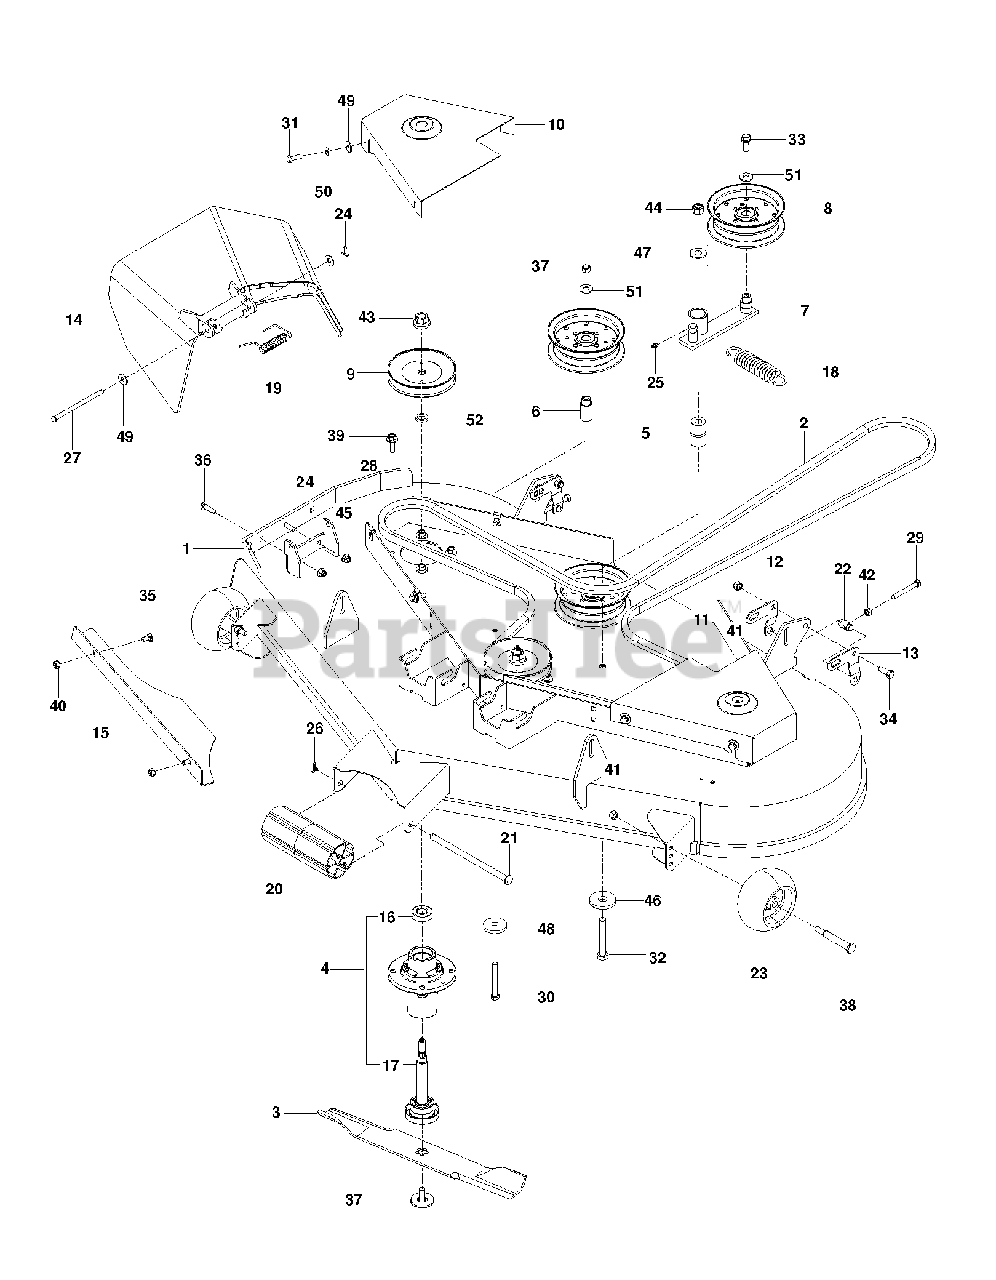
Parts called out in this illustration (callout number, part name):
3	BLADE, 18"
4	MANDREL ASM, CAST IRON
5	PIVOT BUSHING
6	IDLER BUSHING
7	IDLER ARM
8	PULLEY, IDLER
9	PULLEY MANDREL
10	BELTSHIELD.PNT.RH.52.X428
11	BELTSHIELD.PNT.LH.52.BLACK
12	Bracket, RH
13	Bracket, LH
14	DISCHARGE CHUTE 52"
15	CONFINEMENT PLATE, 52"
17	SHAFT ASM MANDREL
19	SPRING - TORSION
20	NOSE ROLLER 48"
21	ROD.ROLLER.NOSE.NARROW.48"
22	TRUNION, PITCH
23	GAUGE WHEEL
24	BRACKET.PNT.MZ.CHUTE.JNX667
25	ZERK
26	COTTER PIN 1/8 X 3/4
27	PIN-CLEVIS 5/16 DIA X 5.19 ZD
28	U-CLIP 5/16-18 NUT RETAINER
29	HCS 5/16-18 X 2 1/2 TPBLT
30	BOLT
32	HCS 1/2C X 3 1/4
33	HCS 3/8C X 1 SERRATED HEAD
34	HCS 3/8C X 1
35	BOLT
37	BLADE BOLT ASSY-7/16" TB REPL
38	BOLT, SHOULDER
39	Hex Washer Head Bolt, .313-18 X 1.19
40	NUT.71038.31-18.HEX.NYLOCK
41	NUT 3/8-16 NYLOC
42	NUT 5/16C HEX
43	LOCKNUT - 9/16
44	NUT 1/2-13 HEX NYLOC ZD
45	5/16-18 NYLOC FLANGE NUT
46	WASHER, SUPPORT
47	WASHER 1/2 FLAT
48	SPINDLE WASHER
49	WASHER
50	Lock Washer, 5/16
51	WASHER 3/8 FLAT
52	WASHER-SPACER
